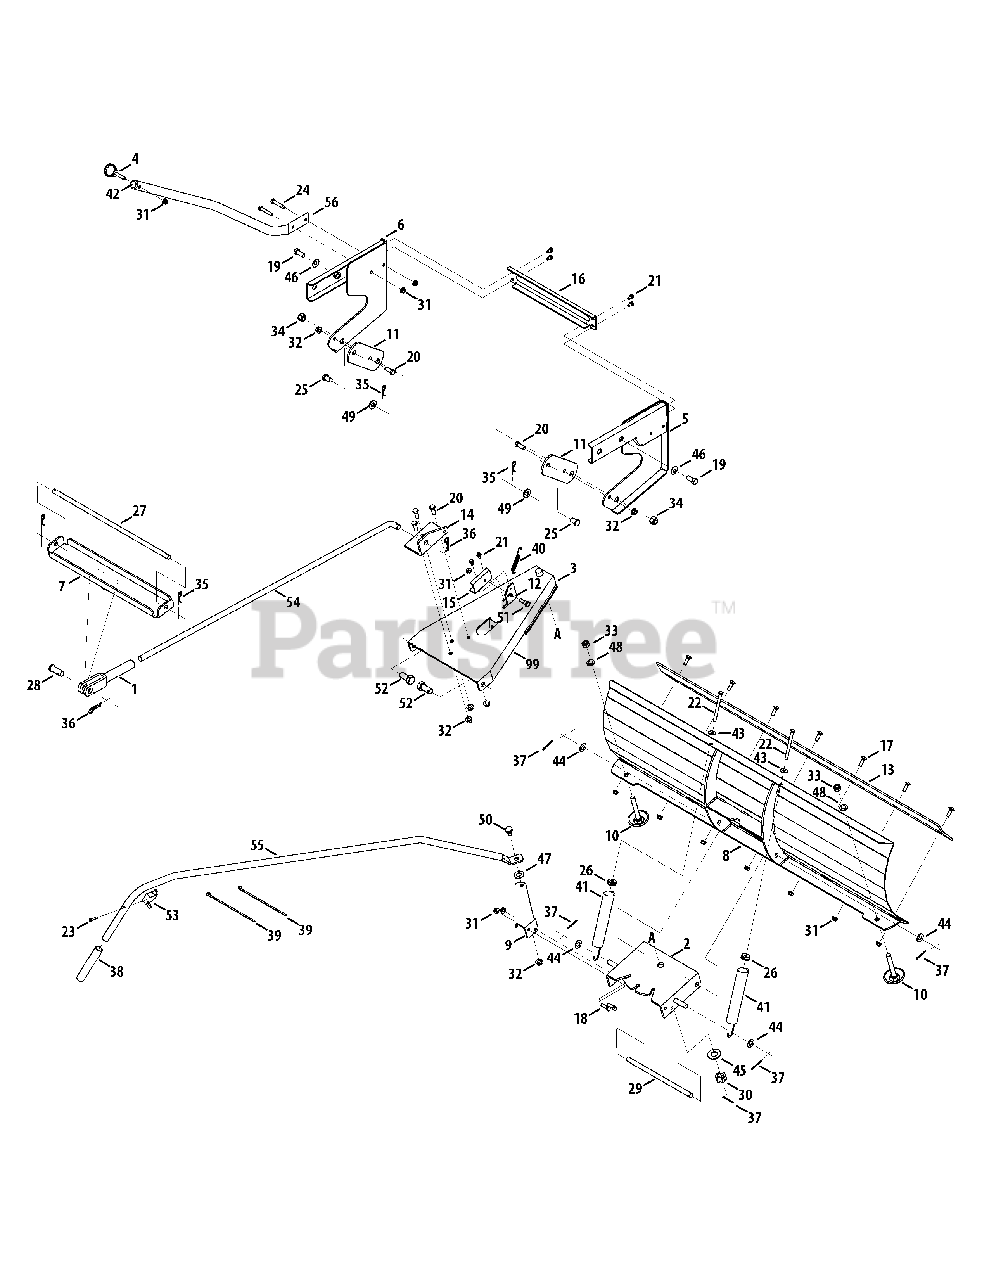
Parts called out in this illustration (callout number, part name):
1	Adjustment Clevis Assembly
4	Eye Bolt Assembly
10	Skid Shoe Assembly
12	Blade Lock Plate
17	Carriage Screw, 5.16-18 x 1.00
18	Hex Screw, 7.16-14 x 1.00
19	Hex Screw, 3.8-16 x 1.00
20	Hex Washer Screw, 1.4-20 x .500
21	Hex Screw, 5.16-18 x 3.50
22	Machine Screw, #10-24 x 1.375
23	Hex Screw, 5.16-18 x 1.00
24	Hex Screw, 5.16-18 x 1.75
25	Clevis Pin, .50 x .78
26	Spring Insert
27	Rod, .50 x 18.61
28	Clevis Pin
29	Rod, .50 x 10.428
30	Slotted Nut, 3.4-16
31	Flange Lock Nut, 5.16-18
32	Flange Lock Nut, 3.8-16
33	Jam Nut, 1.2-13
34	Hex Lock Nut, 1.2-13
35	Click Pin, .092 x 1.64
36	Cotter Pin, .125 x 1.75
37	Cotter Pin, 1.8 x 1.25
38	Foam Grip
39	Cable Tie, 3.16 x .05 x 7.4
40	Extension Spring, .38 x 3.25
41	Extension Spring, 1.25 x 6.7
43	Flat Washer, .349 x .879 x .063
44	Flat Washer, .53 x .93 x .050
45	Flat Washer, .760 x 1.50 x .120
46	Bell Washer, .45 x 1.00 x .062
47	Flat Washer, .570 x 1.120 x .062
48	Lock Washer, 1.2
49	Flat Washer, .531 x 1.062 x .134
50	Shoulder Bolt, 3.8-16 x .496 x .336
51	Shoulder Screw, 5.16-18 x .405 x .435
52	Shoulder Screw, 1.2-13 x .625 x .36
53	Blade Release Cable
